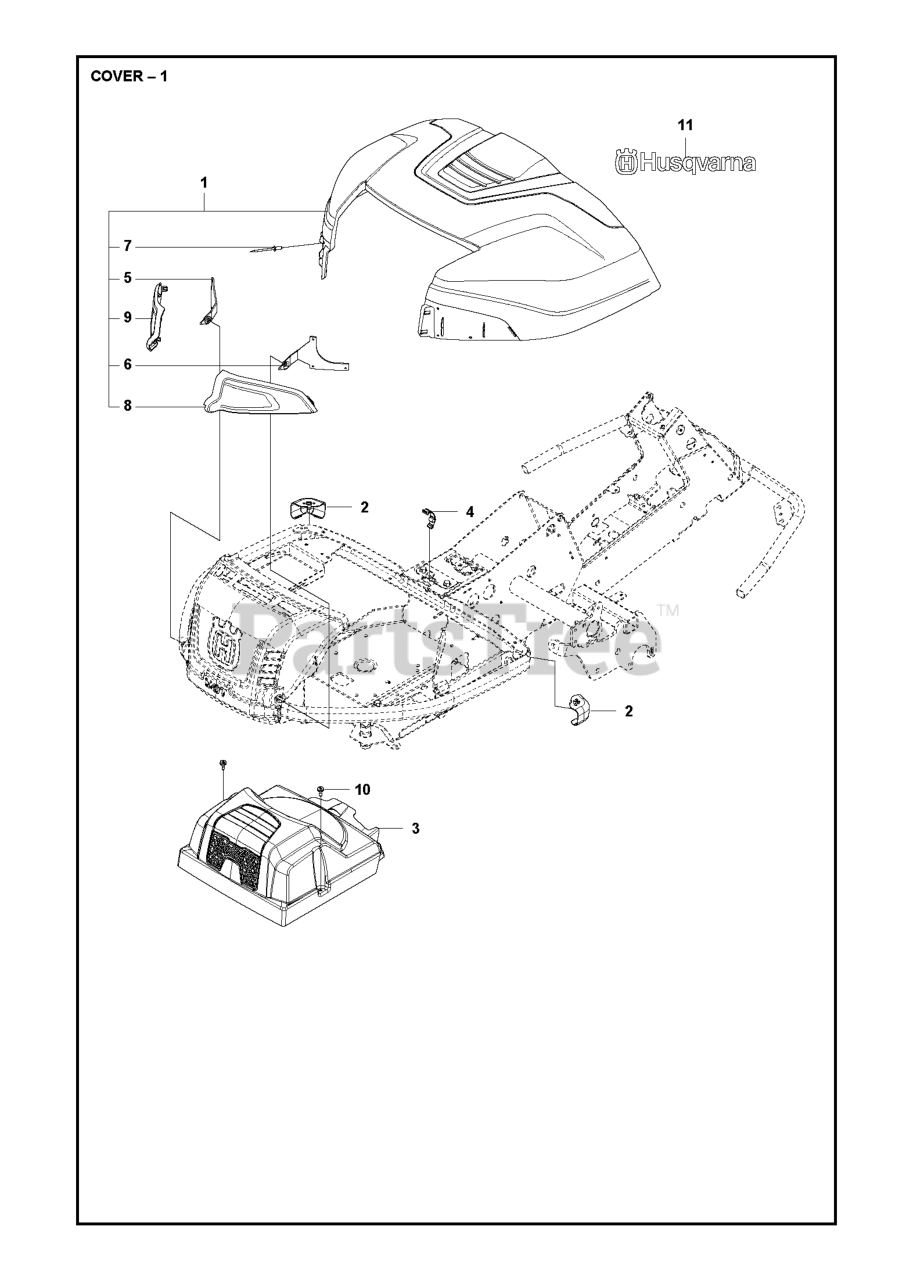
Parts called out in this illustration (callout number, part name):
1	ENGINE HOOD ASSY
3	TRANSMISSION COVER
10	SCREW
